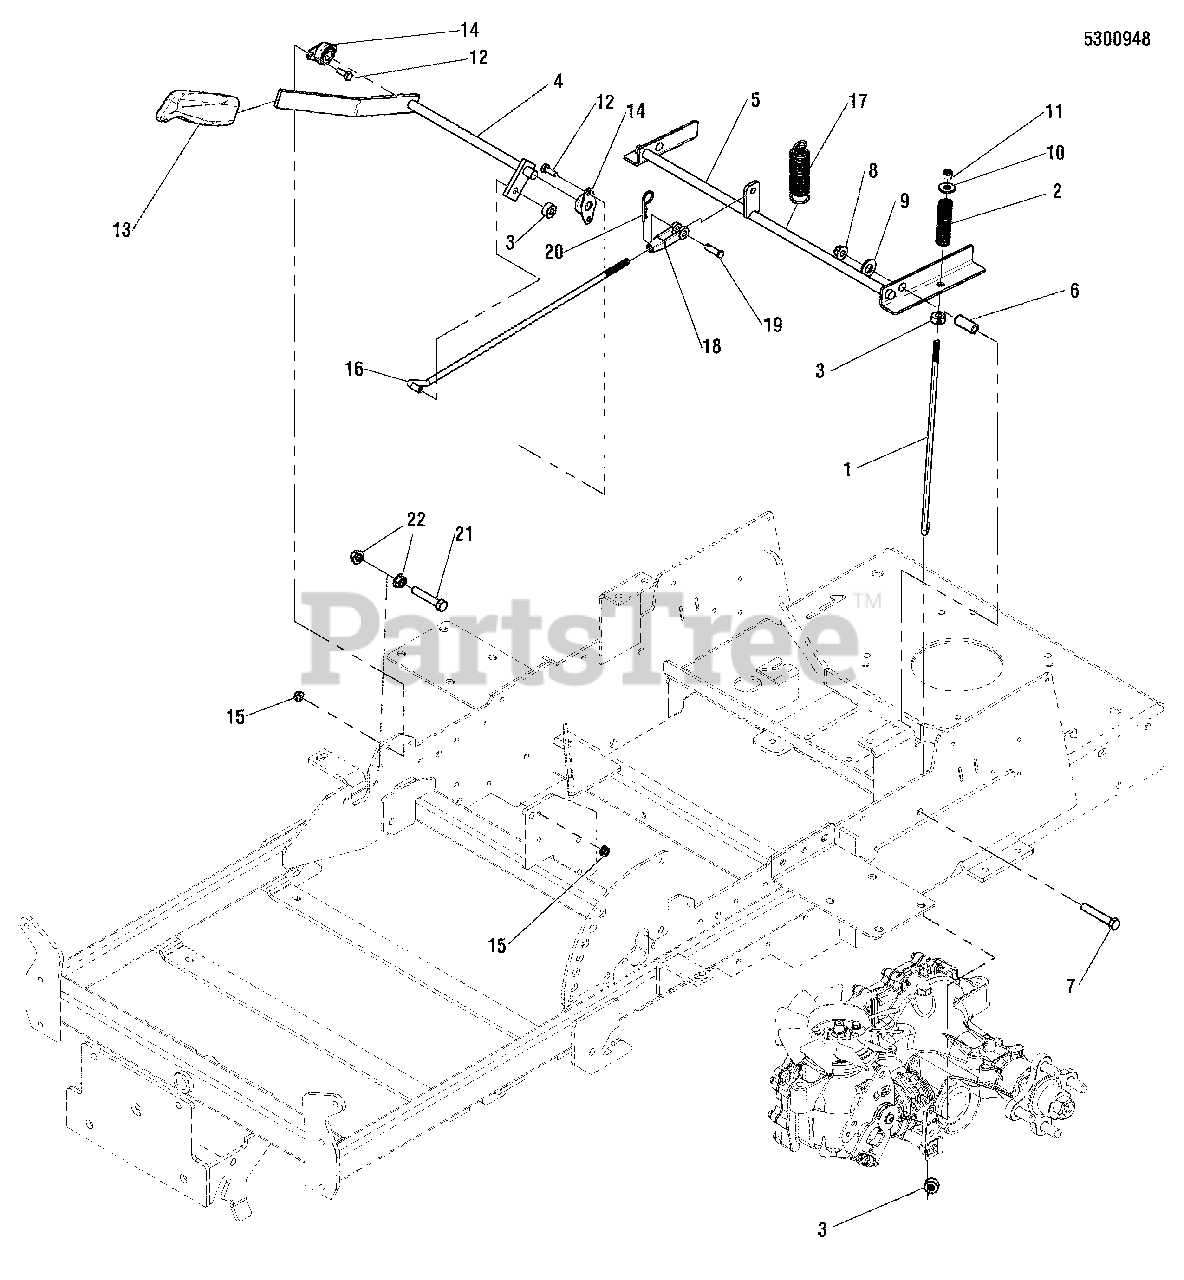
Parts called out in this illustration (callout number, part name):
1	ROD, BRAKE CTRL, LOWER - CONZ
2	SPRING, COMPRESSION
3	COLLAR, 5/16" SET
4	WELD, SHAFT, BRAKE HANDLE - ORG
5	WELD, BRAKE SHAFT - ORG
6	SPACER, .38 X .50 X 1.56
7	BOLT, 3/8-16 X 2-1/4 GD5 YZ
8	NUT, 3/8-16 HEX NYLOCK FLANGE
9	WASHER, 1/2 SAE
10	WASHER, 5/16 USS
11	NUT, 5/16-24 HEX NYLON LOCK
12	BOLT, 1/4-20 X 3/4 GD5 YZ
13	GRIP, BLACK FLEXIBLE
14	BEARING, 1/2" FLANGED
15	NUT, 1/4-20 HEX NYLOCK FLANGE (5025391)
16	ROD, PULLER ROD
17	SPRING-EXTN 1.040ODX 04.000LG .105WIRE D
18	CLEVIS, 5/16-24, STEEL
19	PIN, CLEVIS, 5/16 X 1 YZ
20	PIN, HAIR, .0915 X 1-7/8
21	BOLT, 3/8-16 X 2 GD5 YZ
22	NUT, 3/8-16 HEX SERRATED FLANGE
